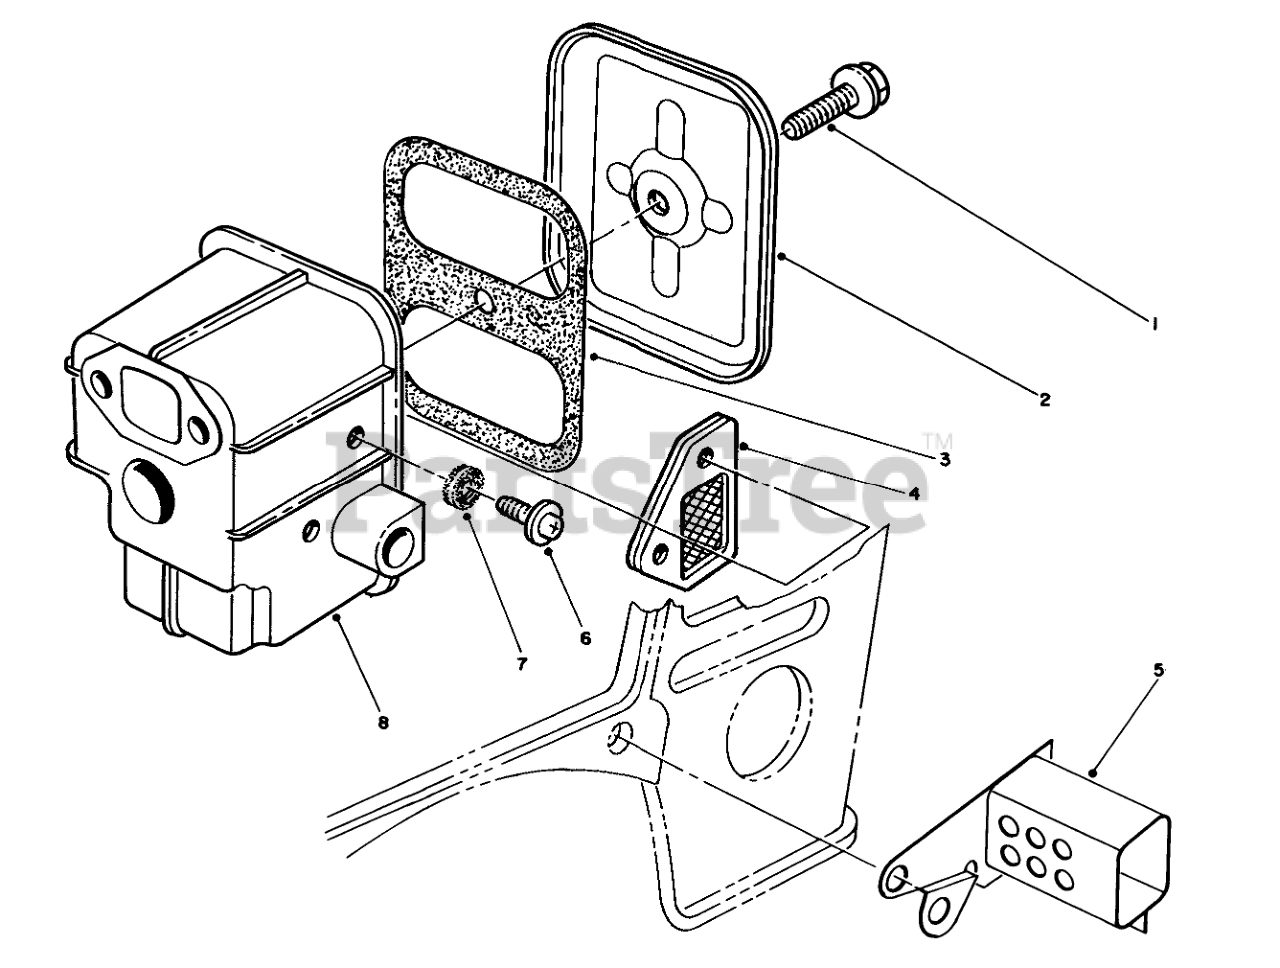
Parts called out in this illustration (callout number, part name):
2	Lid-Muffler
3	MUFFLER GASKET
4	Spark Arrestor
5	Cover-Muffler
6	Screw & Washer
7	Gasket
8	Body-Muffler
